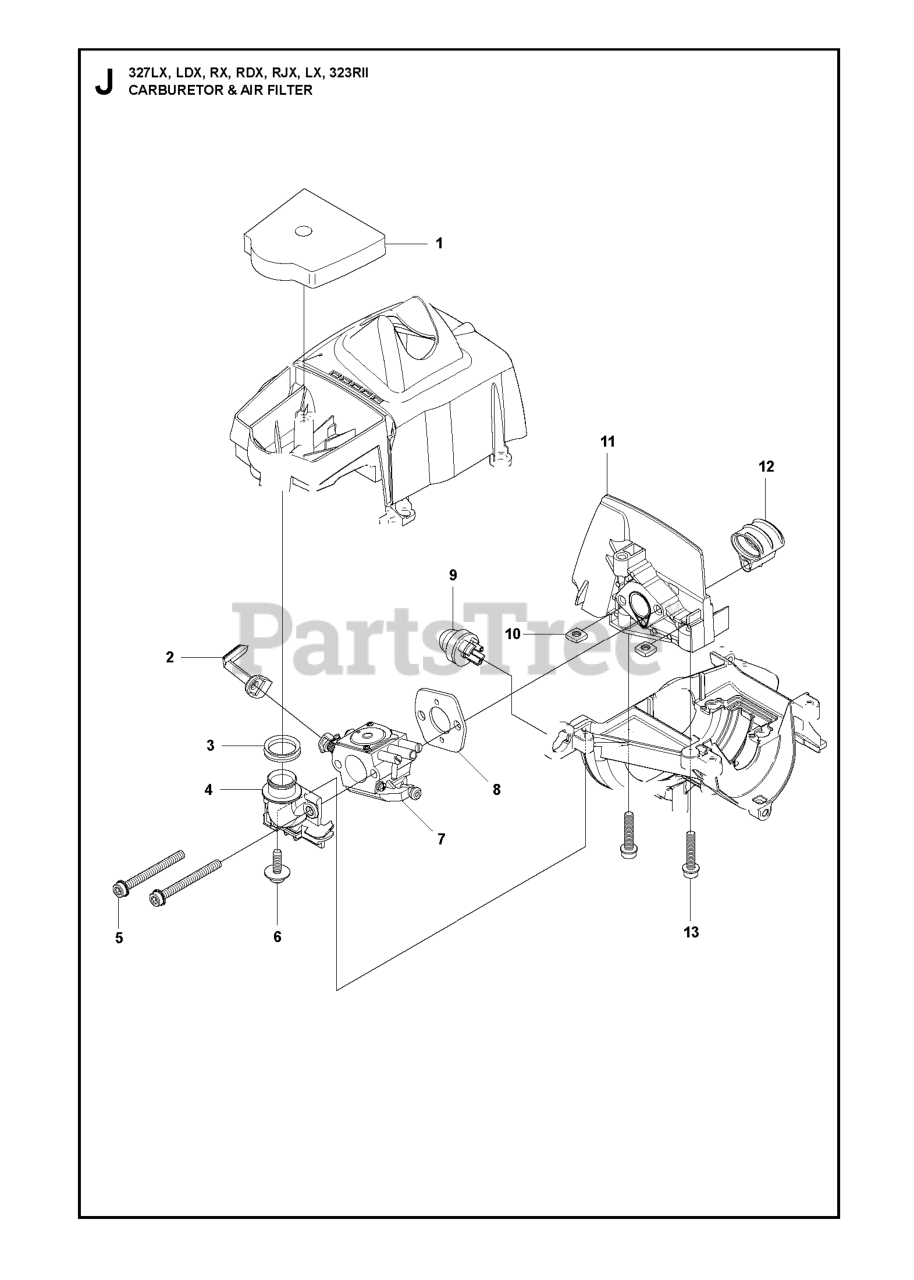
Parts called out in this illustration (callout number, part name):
1	AIR FILTER
2	CHOKE CONTROL
7	CARBURETOR
9	AIR PURGE BUBBLE
